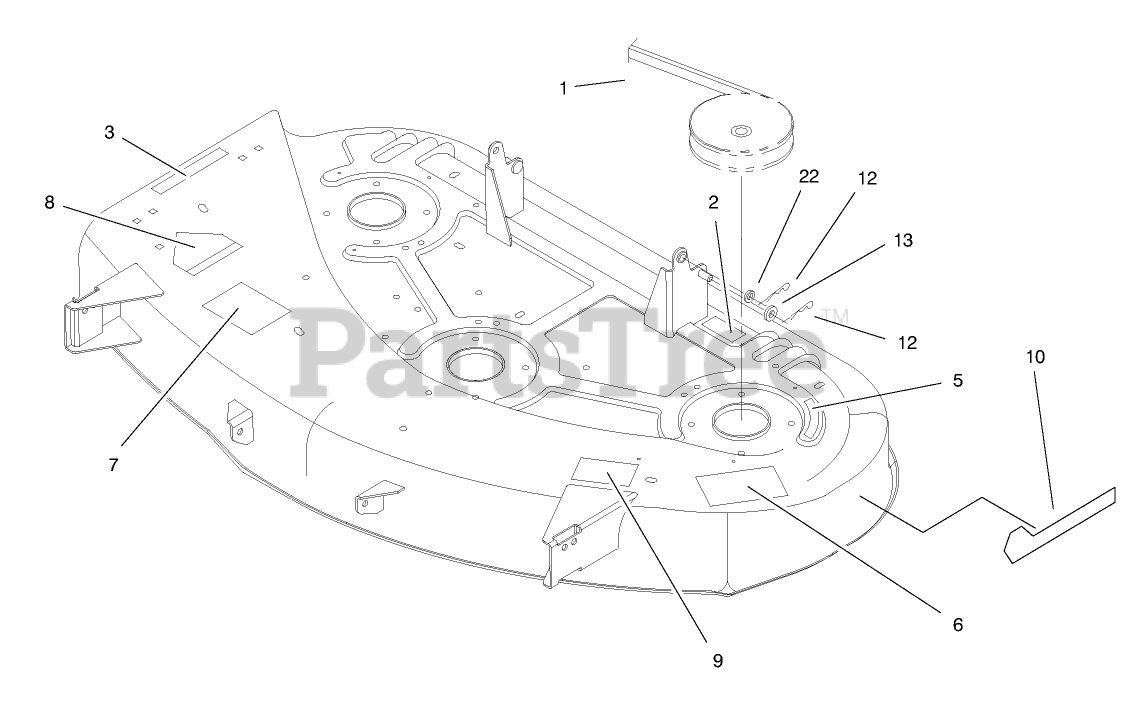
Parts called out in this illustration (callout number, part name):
1	V BELT-DECK
2	DECAL-WARNING
3	DECAL-DANGER, DEFLECTOR
5	DECAL-DANGER, SHIELD
6	DECAL-DANGER, THROWN OBJECT
7	DECAL-INSTALLATION, BELT
8	DECAL-DANGER
9	DECAL-ADJUSTMENT, WHEEL
10	DECAL - RECYCLER DECK
13	WASHER-HARDENED
22	WASHER-FLAT
